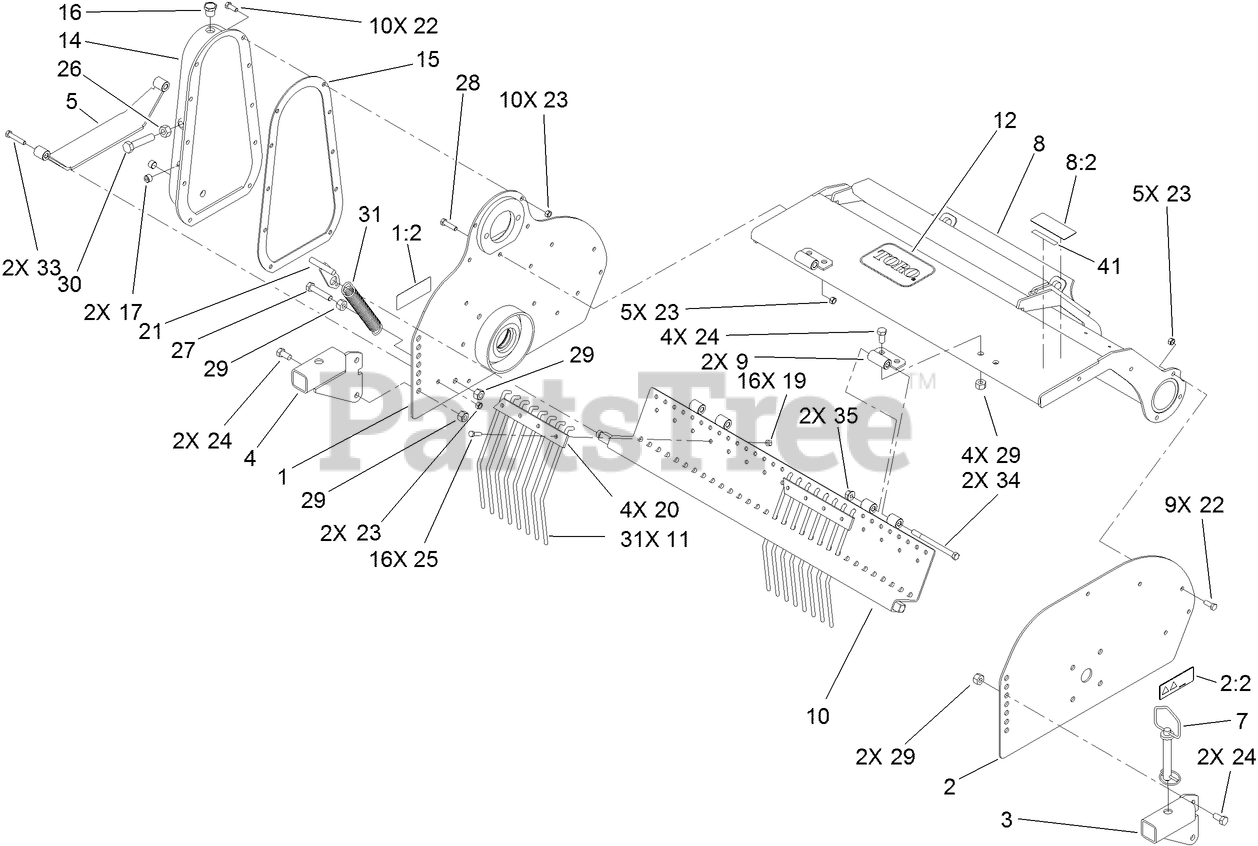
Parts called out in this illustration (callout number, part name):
1	LEFT SIDE ASM
1:2	DECAL-DANGER
2	RIGHT SIDE ASM
2:2	DECAL-DANGER
3	PLATE-FITTING, RIGHT
4	PLATE-FITTING, LEFT
5	PLATE-PROTECTOR
7	PIN-DRIFT
8	FRAME CHASIS ASM
8:2	DECAL-WARNING
10	PLATE-ROD, SCREENING
11	ROD-SCREENING
12	DECAL
14	CASE-CHAIN
15	GASKET-CORK
19	NUT-LOCK, NI
20	PLATE-RETAINING, TINE
21	HANDLE-SPRING
22	SCREW-HH
23	NUT-HEX
24	SCREW-HH
25	SCREW-HH
26	NUT-HEX
27	SCREW-HH
28	SCREW-HH
29	NUT-LOCK, NI
30	SCREW-HH
31	SPRING-EXTENSION
33	SCREW-HH
34	SCREW-HH
35	NUT-LOCK, HHF
41	DECAL-WARNING
